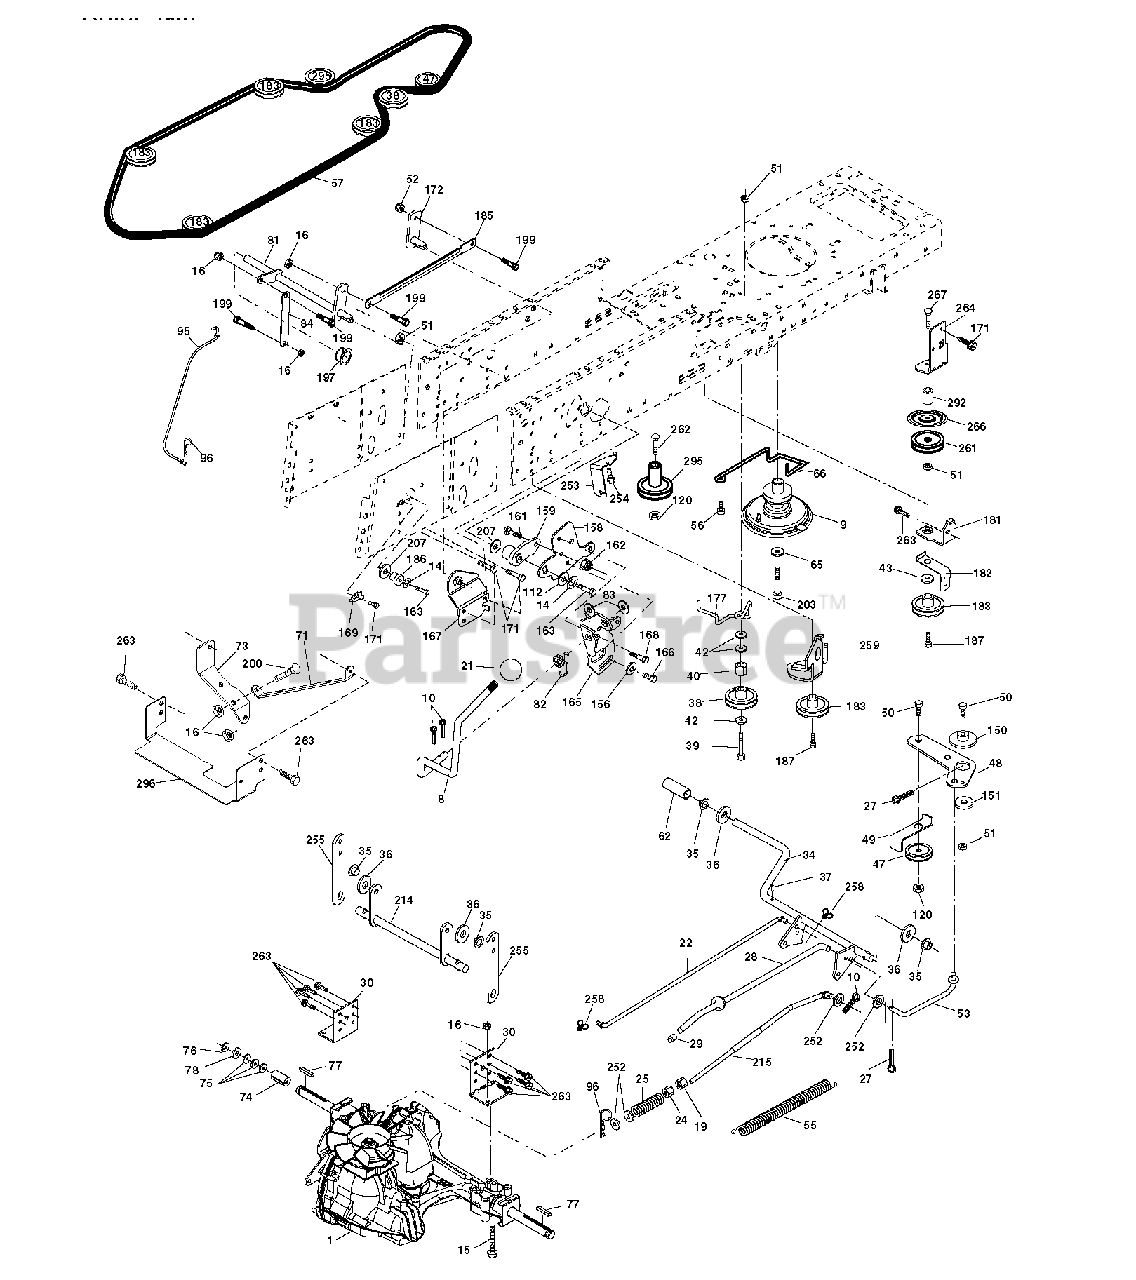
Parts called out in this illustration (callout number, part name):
8	ROD SHIFT FENDER ADJUST LT
10	PIN COTTER
14	LOCKWASHER
15	BOLT HEX 5/16-18 GR 5
16	NUT.71038.31-18.HEX.NYLOCK
19	NUT
21	PISTOL KNOB
24	NUT
27	COTTER PIN
28	ROD, PARKING BRAKE
29	PLUNGER CAP
30	BRKT, TRNSXLE MNT 20"
34	SHAFT, FOOT PEDAL
35	BEARING.NYLON
36	WASHER LT
37	DRIVE PIN
38	PULLEY.FLAT
42	WASHER
47	IDLER PULLEY
48	BELLCRANK, CLUTCH
49	RETAIN BELT
50	BOLT.3/8-16X1.50
51	LOCKNUT
52	LOCKNUT
53	LINK.CLUTCH.7.66.2005
55	SPRING, RETURN LT
56	SCREW.3/8-16
62	PEDAL COVER T
65	LOCKWASHER
66	KEEPER BELT ENGINE
71	STRAP TORQUE LH HYDRO
73	STRAP TORQUE RH HYDRO
74	SPACER AXLE
76	E-RING LT
77	SQUARE KEY
81	SHAFT ASSY
82	SHIFT SPRING
83	WASHER
96	RETAINER M
112	WASHER LT
120	NUT LOCK FLG 3/8-16 UNC
150	BUSHING.BELLCRANK.GRD.DR
151	WASHER 12/32X2X10GA
156	WASHER.SRRTD.5/16
158	BRACKET
159	HUB.SHIFT
161	BOLT
162	NUT.CROWNLOCK.1/4
165	RP BRACKET
167	BRACKET
168	BOLT.SHOULDER.5/16-18X
169	PLATE.FASTENING.CROSS.SHAFT
187	BOLT.5/16-18X1.25
197	NYLINER SNAP 5/8" ID
199	BOLT SHOULDER 5/16-18 UNC
200	BOLT
207	WASHER NYL
254	SCREW 3/8-16X1
258	CLIP RETAINER
261	FLAT IDLER PULLEY
263	SCREW, 3/8-16X3/4
295	PULLEY IDLER COMPOSITE
